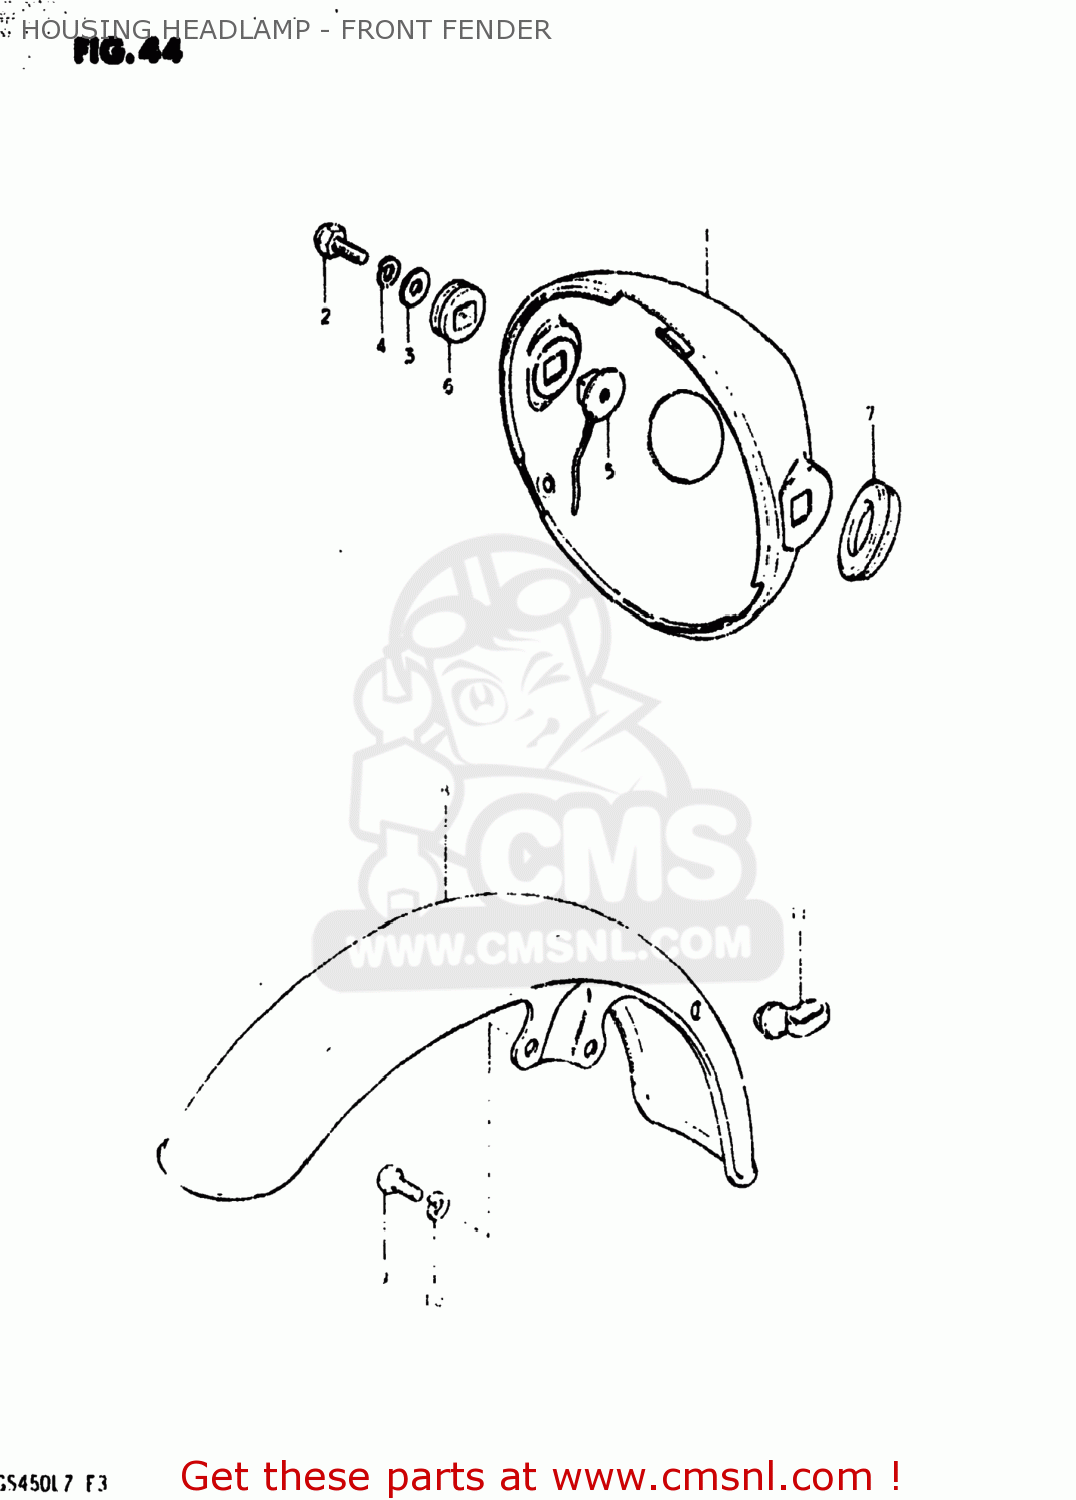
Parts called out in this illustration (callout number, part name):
1	HOUSING,HEADLAMP
2	BOLT
3	WASHER
4	LOCK WASHER
5	SPACER,HEADLAMP HOUSING
6	CUSHION,HEADLAMP HOUSING
7	GROMMET,HEADLAMP HOUSING
8	FENDER,FR
9	BOLT
10	LOCK WASHER
11	GUIDE,CABLE
